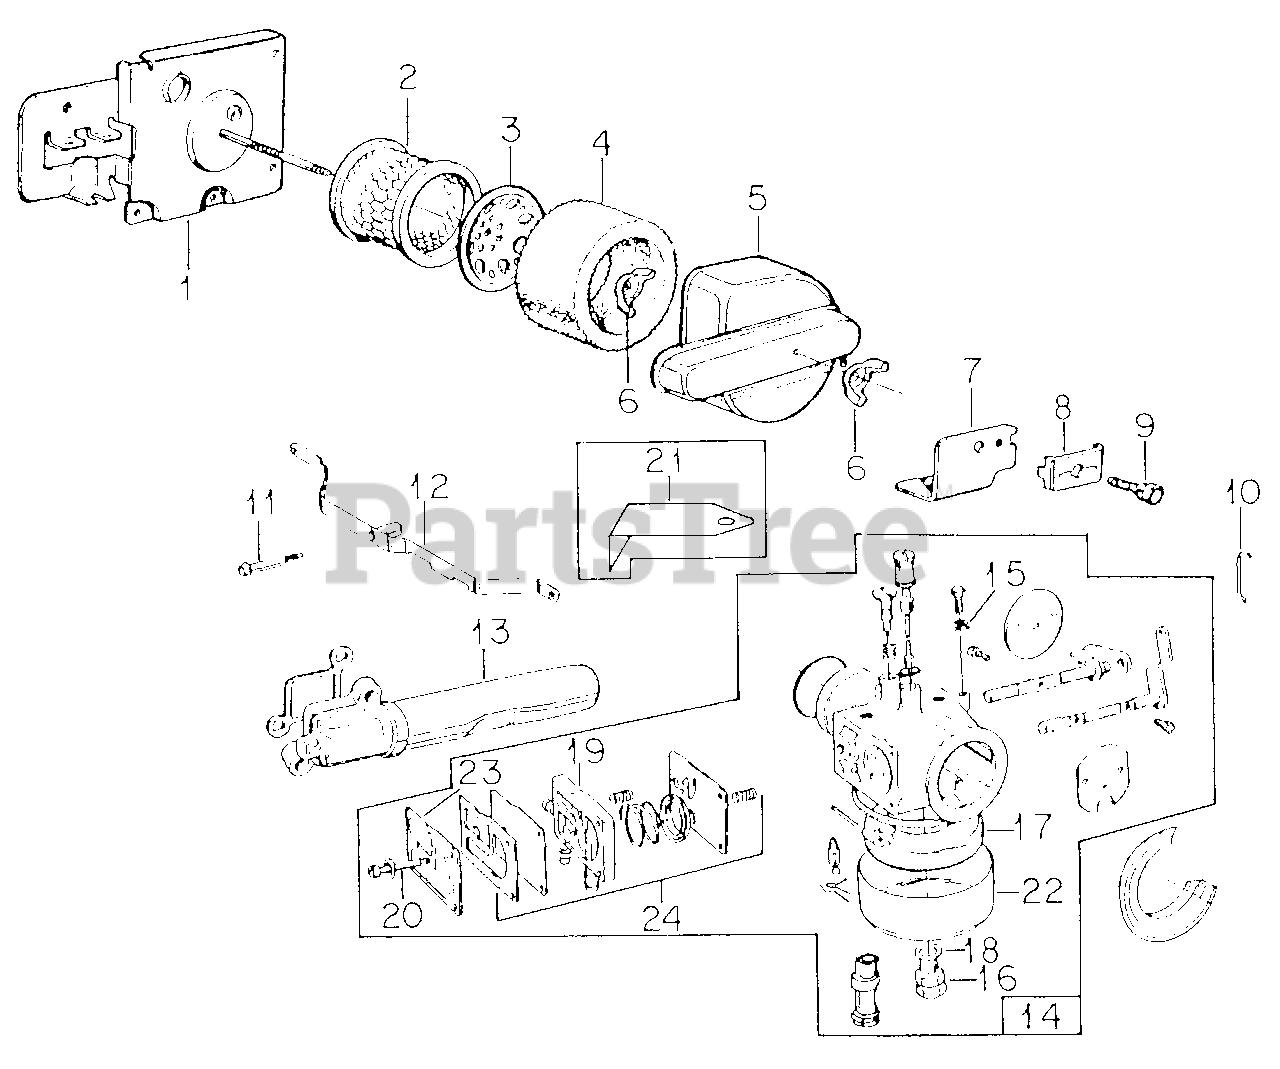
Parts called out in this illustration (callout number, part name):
1	Plate Assy, Air Cleaner Mounting
2	Cartridge, Air Cleaner
3	Cup, Air Cleaner
4	Element, Air Cleaner
5	Cover, Air Cleaner
6	Nut, 1/4-20 Znp Wing
7	Bracket, Choke Control
8	Clamp, Casing
9	Screw, Clamp
10	Link, Throttle
11	Bolt, Shoulder
12	Lever, Linkage
13	Manifold, Intake
14	Carburetor Assy
15	Spring, Throttle Adjusting
16	Screw, Float Bowl Mounting
17	Float Assy
18	Washer, Float Bowl
19	Pump, Body
20	Screw, Pump Cover
21	Bracket, Carburetor Support
22	Bowl, Float
23	Cover, Pump
24	Kit, Pump Repair
